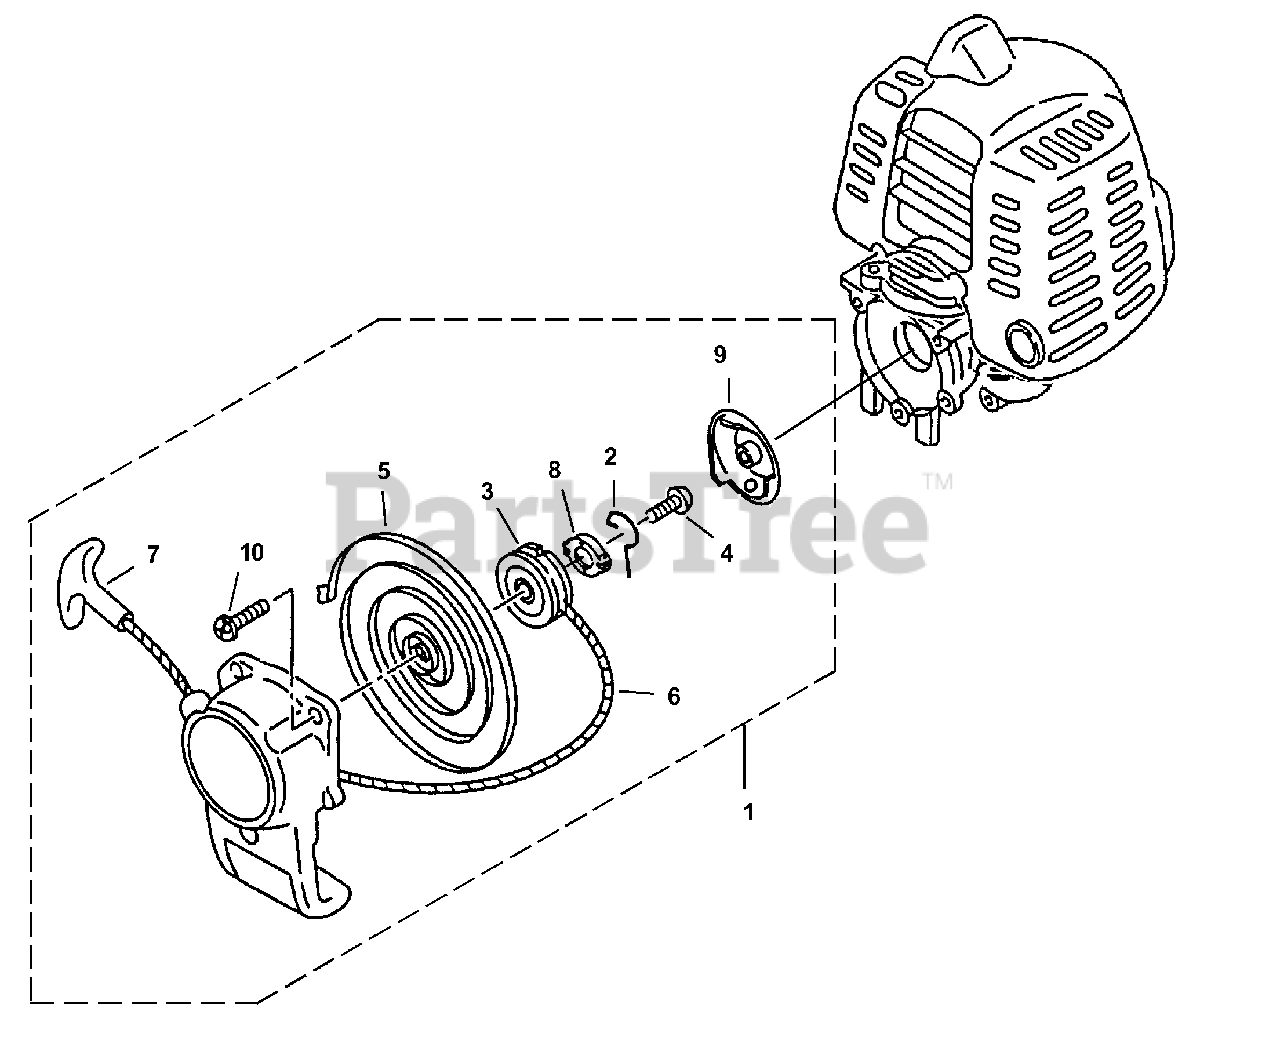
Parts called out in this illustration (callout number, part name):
1	STARTER COMPLETE
2	SWING ARM
4	SCREW-Set
5	SPRING-Return
6	ROPE-Starter
9	STARTER CUP
10	SCREW ASSEMBLY (M4 x 25)
